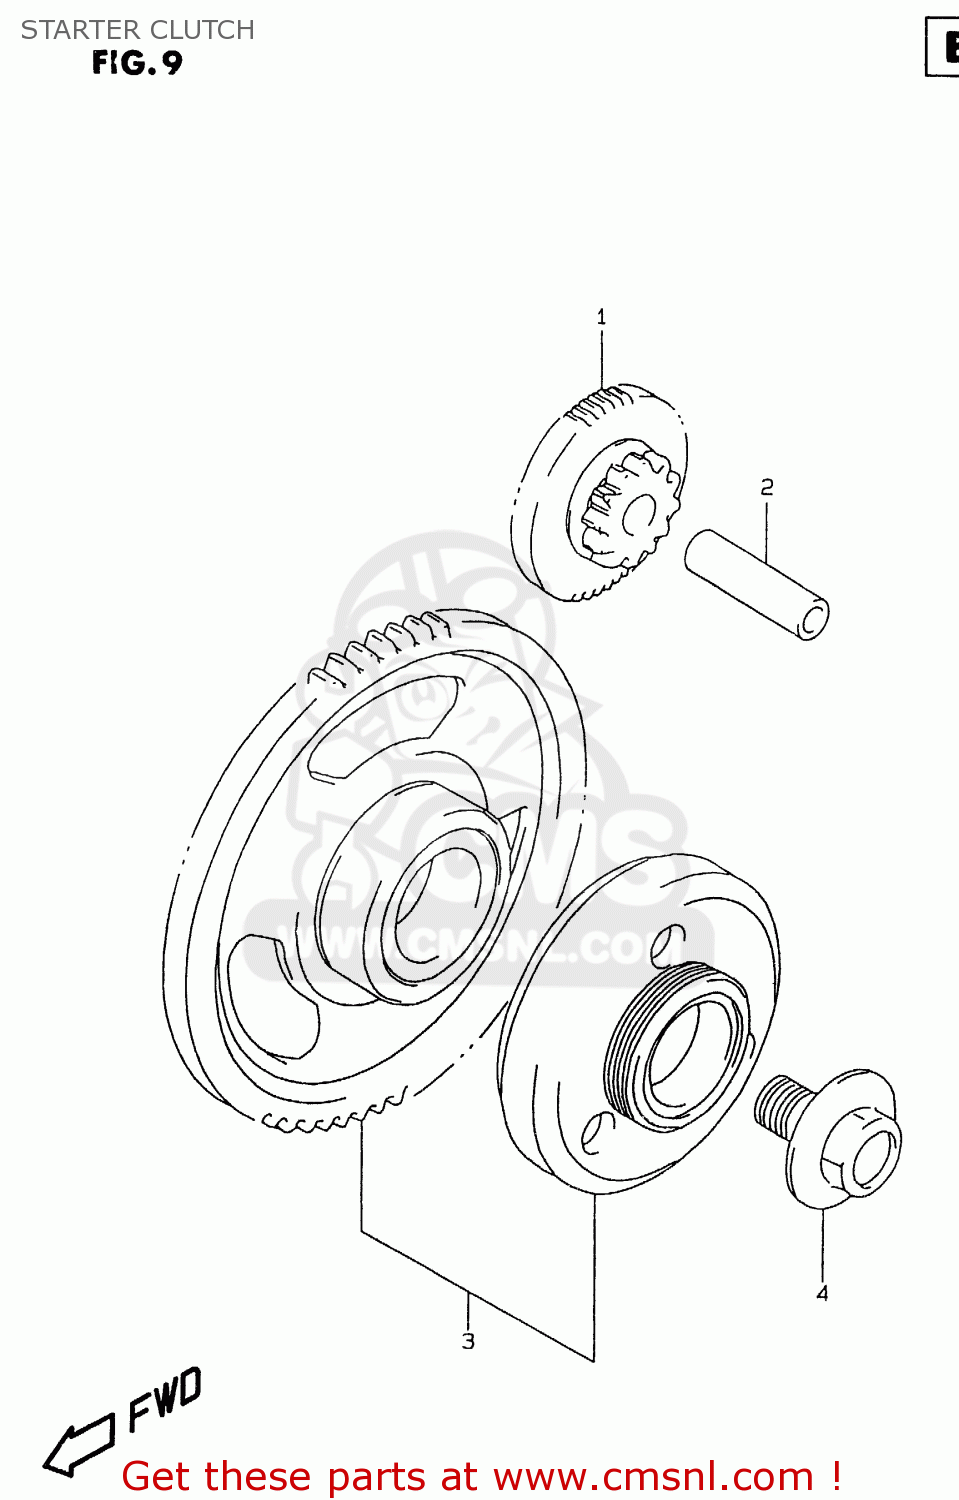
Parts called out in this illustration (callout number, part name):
1	GEAR,STARTER IDLE(NT:12,53)
2	PIN(7X11X42)
3	CLUTCH SET,STARTER
4	BOLT(14X21)
